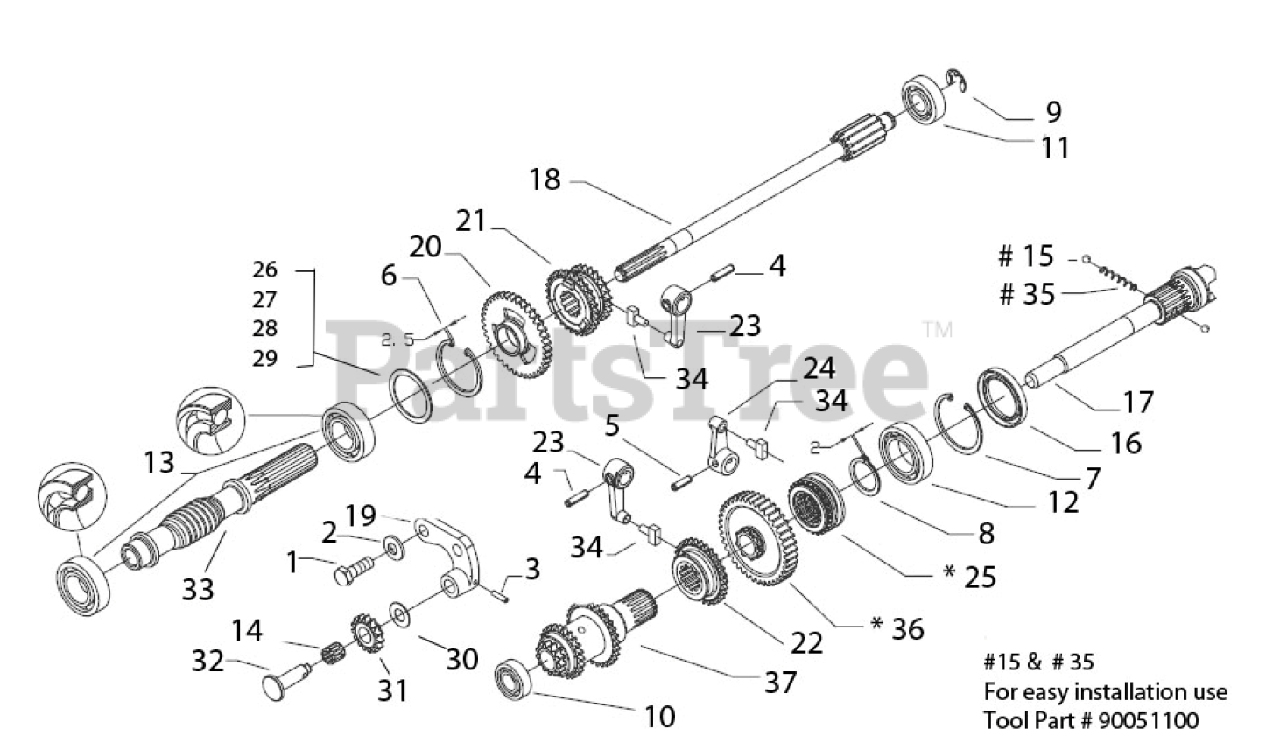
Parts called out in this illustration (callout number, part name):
1	CAP SCREW M10X30
2	WASHER , SUPER M10
3	PIN , SPLIT
4	PIN SPIRAL SPLIT
5	PIN SPIRAL SPLIT
6	SNAP RING D52
7	SNAP RING D55
8	SNAP RING D31
9	RING , SPLIT
10	BEARING 15X35X11
11	BEARING 15X42X13
12	BEARING 30X55X13
13	BEARING 25X52X15
14	BEARING 12X15X10
15	BALL 1/4"
16	OIL SEAL 38X55X7
17	SHAFT , PTO
18	MAIN INPUT SHAFT
19	SUPPORT REVERSE GEAR
20	GEAR , FIRST
21	GEAR , SLIDER
22	SLIDER REVERSER
23	LEVER REVERSER
24	LEVER PTO ENGAEMENT
25	PTO SLIDER
26	SHIM 1.5 MM
27	SHIM 1.6 MM
28	SHIM 1.7 MM
29	SHIM 1.8 MM
30	WASHER
31	REVESER GEAR
32	PIN REVERSE GEAR
33	WORM GEAR
35	SPRING FOR PTO BALLS
36	PTO GEAR
36	PTO GEAR KIT, CONSISTS OF 25 & 36
37	GEAR CLUSTER
